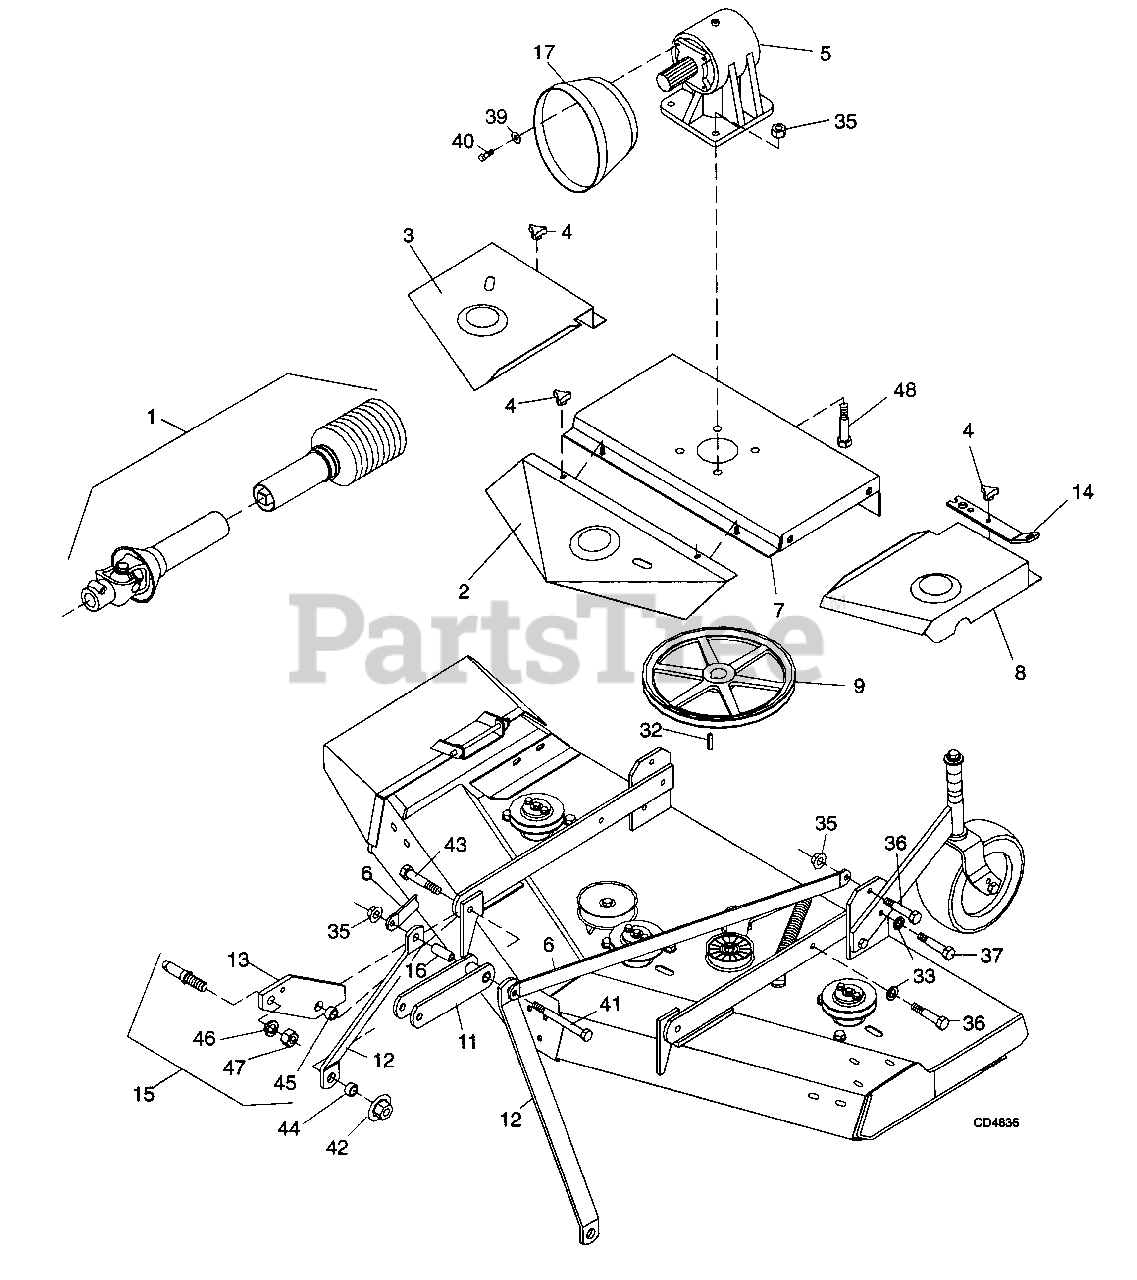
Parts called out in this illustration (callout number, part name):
1	Front and rear drives
2	Shield, front belt
3	Shield, right belt
4	Knob, 3-prong 3/8 NC
5	Gearbox, CW 1:1.76
6	Link, offset .25 x 1.50 x 38.12
7	Gearbox stand
8	Shield, left belt
9	1 BK 13.4 H Sheave, keyed
11	U-Link, .38 x 2.5 x 7.13
12	Link, offset .38 x 2 x 25.88
13	Mounting lug
14	Blade spindle wrench
15	Category 1 mounting pin with nuts and lockwasher
16	Pipe, 1/2 schedule 40 x 2.75
32	1/4 x 1/4 x 1-1/4 Key
33	1/2 Extra-heavy lockwasher
35	1/2 NC Flanged hex locknut
36	1/2 NC x 2-1/4 Hex head cap screw GR5
37	1/2 NC x 2-1/4 Hex head cap screw GR5
39	1/4 Standard flat washer
40	8mm x 1.25P x 20mm Hex head cap screw
41	1/2 NC x 4-3/4 Hex head cap screw GR5
42	5/8 NC Hex locknut, flanged
43	5/8 NC x 3 Hex head cap screw GR5
44	5/8 x 1 7/16 HT Sleeve
45	5/8 x 1 x 9/16 HT Sleeve
46	7/8 Lockwasher
47	7/8 NF Hex nut
48	5/8 x 1-3/4 Hex head cap screw, flanged
